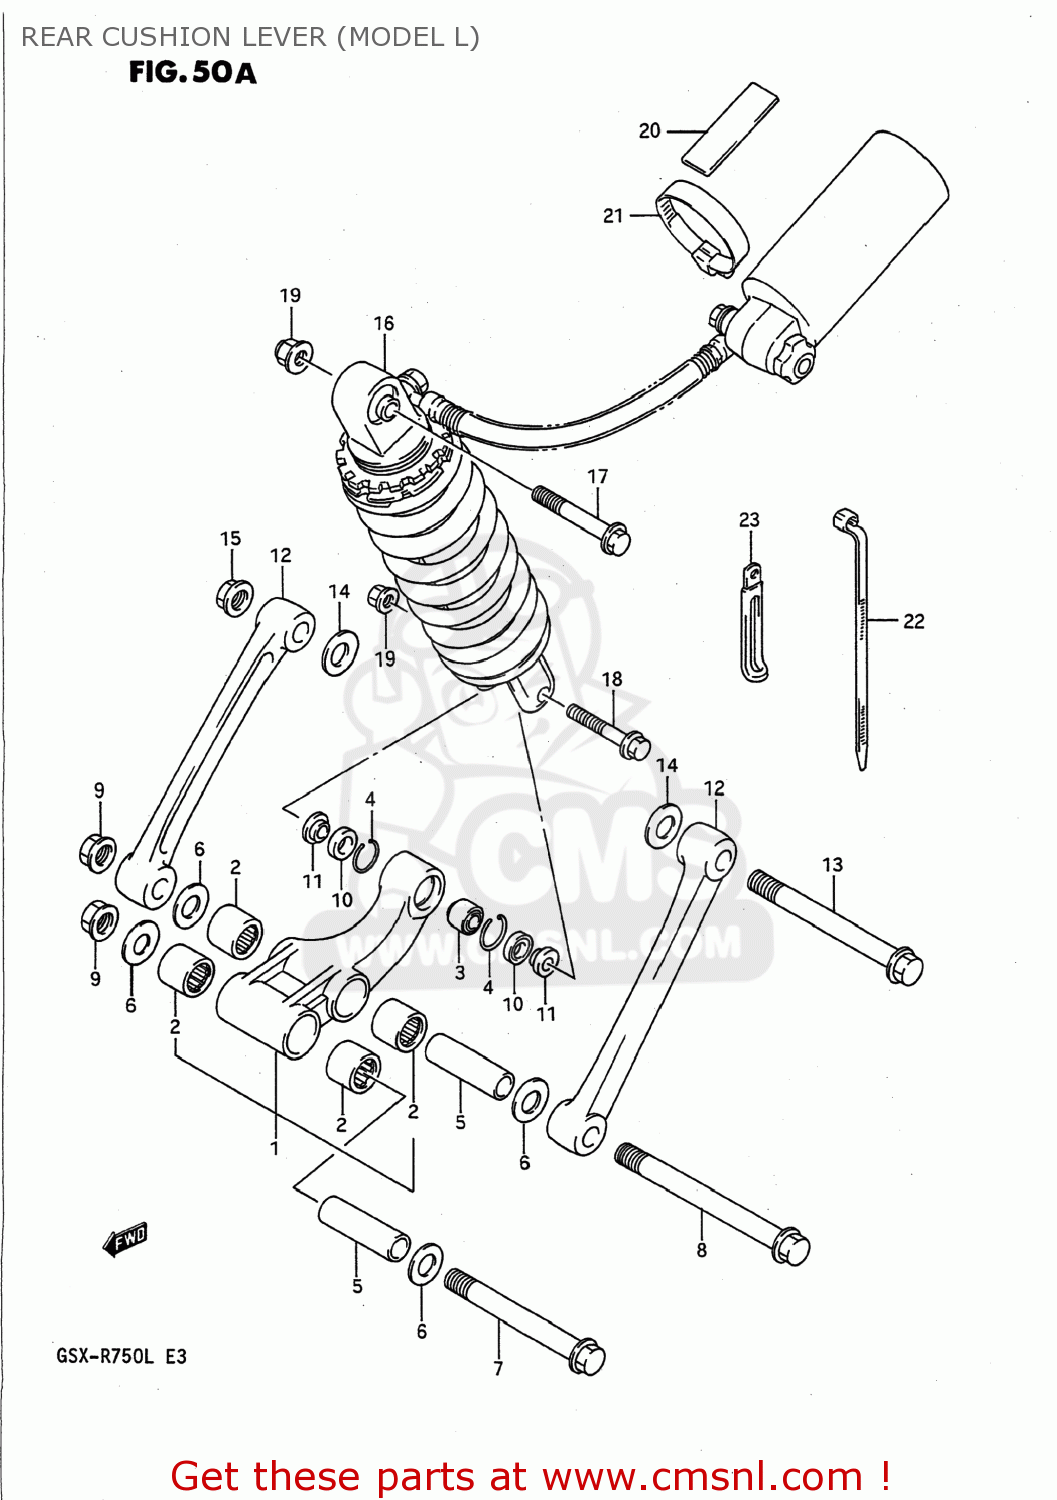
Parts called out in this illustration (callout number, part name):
1	LEVER SET,REAR CUSHION
2	BEARING(20X27X23.5)
3	BEARING,RR CUSHION LEVER
4	RING,STOPPER
5	SPACER,RR CUSHION LEVER
6	WASHER
7	SHAFT,RR CUSHION LEVER FR
8	SHAFT,RR CUSHION ROD
9	NUT
10	DUST SEAL,RR CUSHION LEVER RR
11	SPACER
12	ROD,REAR CUSHION
13	SHAFT,RR CUSHION ROD
14	WASHER
15	NUT
16	ABSORBER ASSEMBLY,REAR SHOCK
17	BOLT
18	BOLT(10X54)
19	NUT
20	CUSHION,RESERVOIR TANK
21	CLAMP
22	CLAMP(L:165)
23	CLAMP
